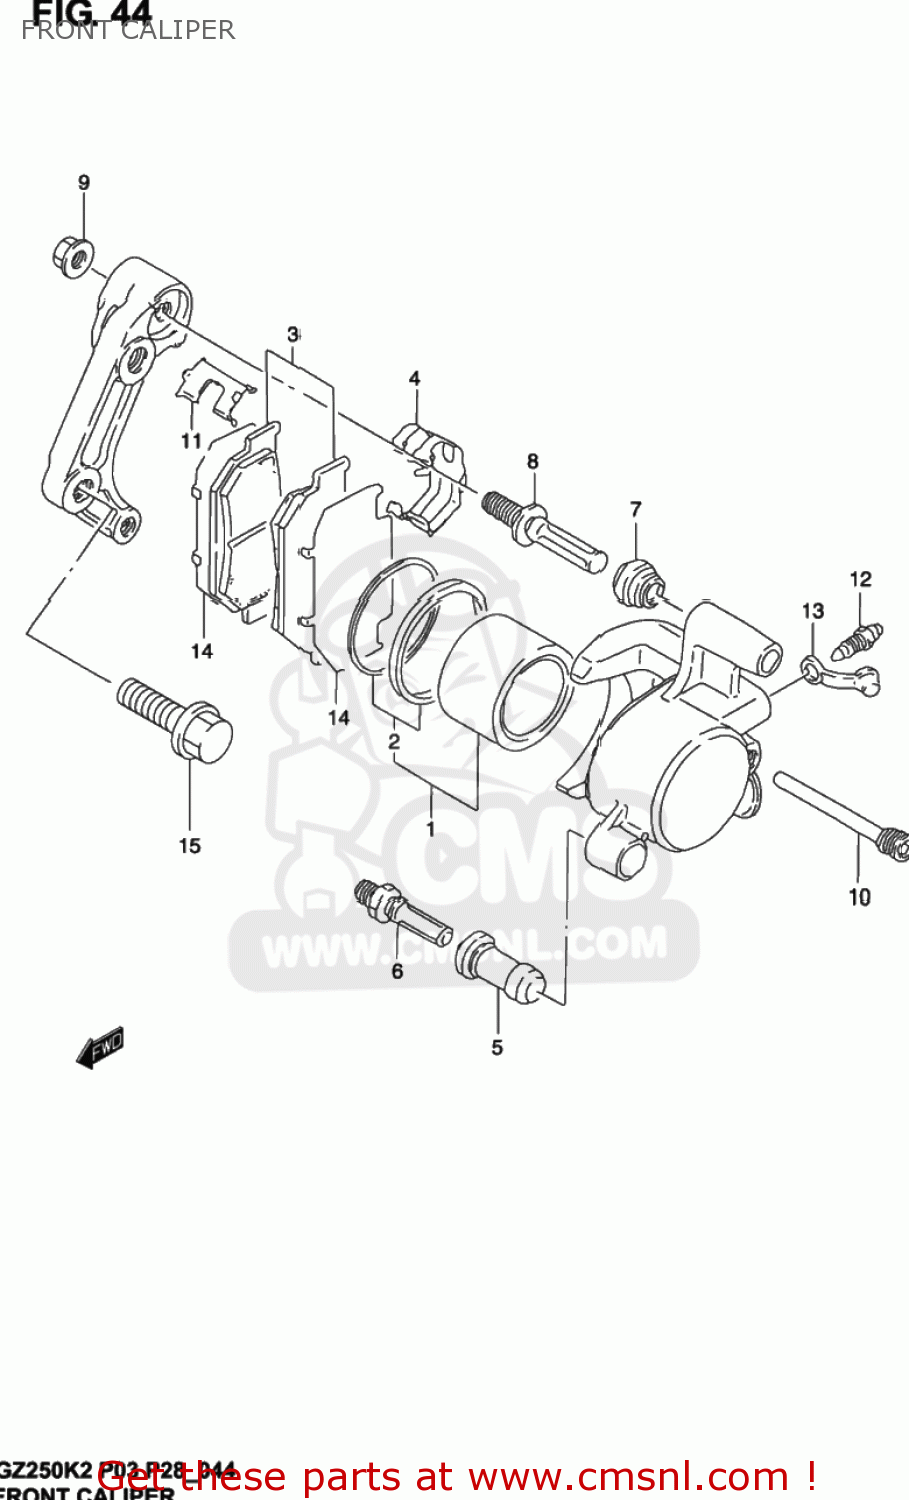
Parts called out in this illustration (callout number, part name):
1	PISTON SET
2	.SEAL SET, PISTON
3	BRAKEPADSET
4	SPRING
5	BOOT
6	PIN
7	BOOT
8	BOLT
9	NUT
10	PIN
11	RETAINER
12	BLEEDER
13	CAP
14	SHIM
15	BOLT
